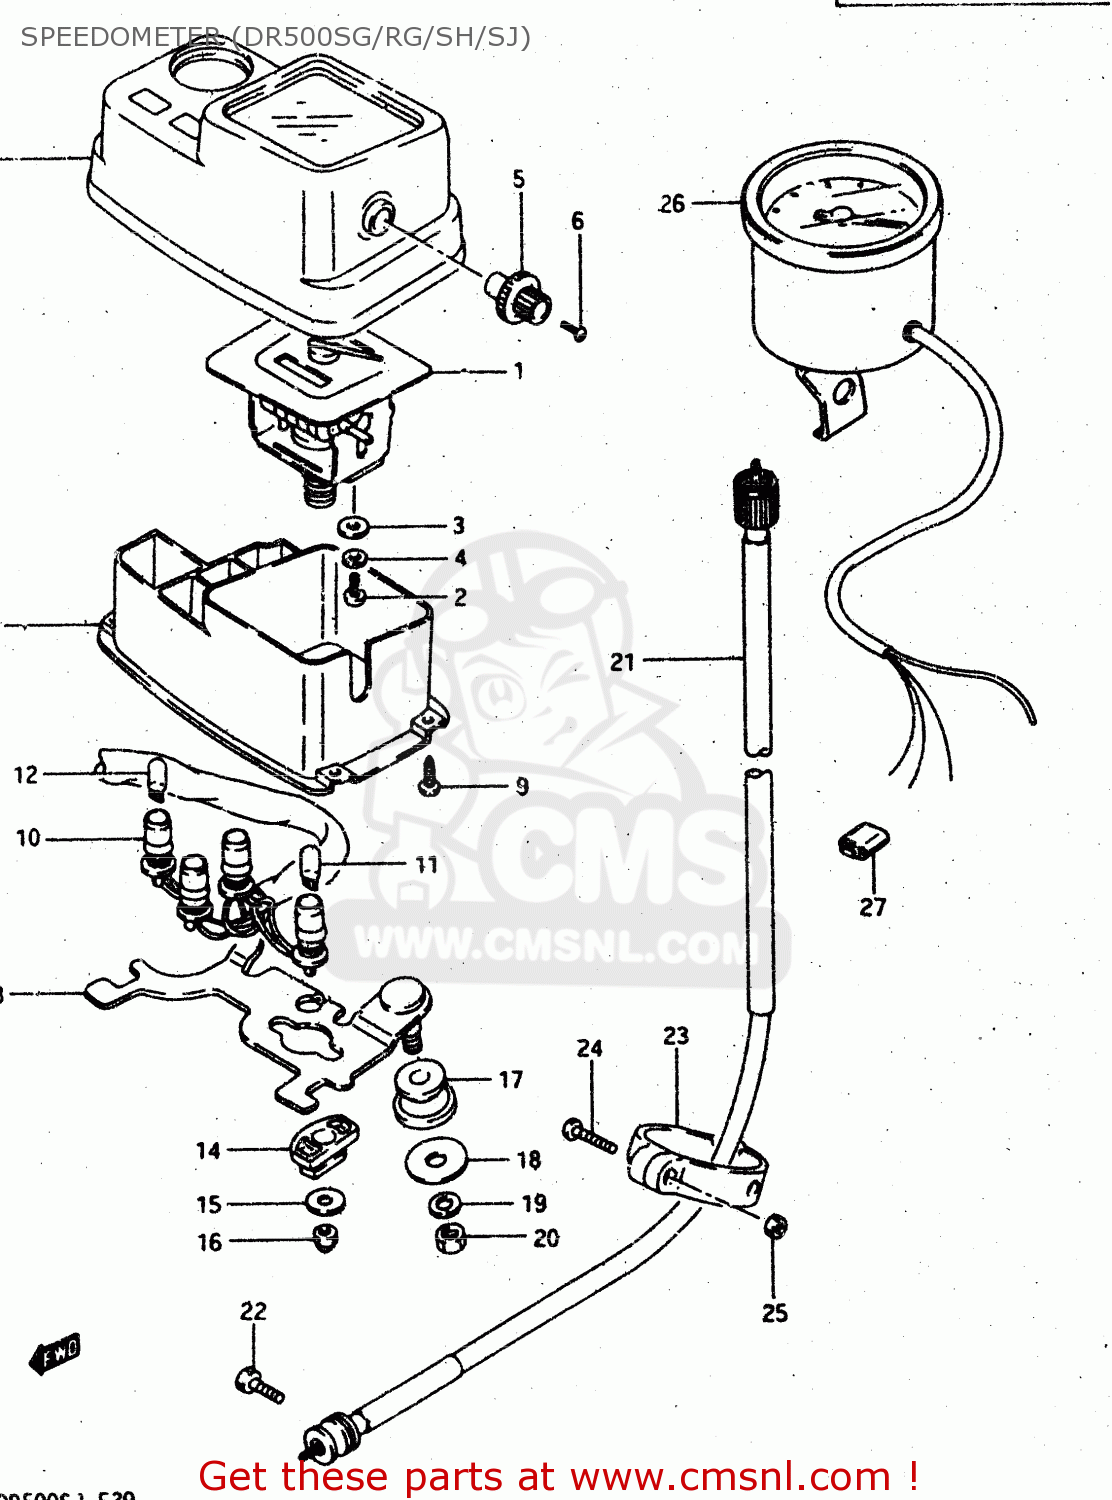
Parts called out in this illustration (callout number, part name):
1	SPEEDOMETER (KILO)
2	SCREW
3	WASHER
4	LOCK WASHER
5	KNOB,TRIP
6	ROTOR,SPEED
7	HOOD,METER
8	CASE,METER
9	SCREW
10	SOCKET,METER
11	BULB(12V3.4W,T10)
12	BULB(12V1.7W,T10,WB121)
13	BRACKET,METER
14	CUSHION
15	WASHER
16	NUT
17	CUSHION,METER BRACKET
18	WASHER (8.5X20X1.6)
19	WASHER,LOCK,8.
20	NUT
21	CABLE ASSEMBLY,SPEEDOMETER
22	BOLT
23	CLAMP,SPEEDOMETER CABLE
24	SCREW 5X20
25	NUT
26	METER,TACHOMETER
27	CONNECTOR,LEAD WIRE
